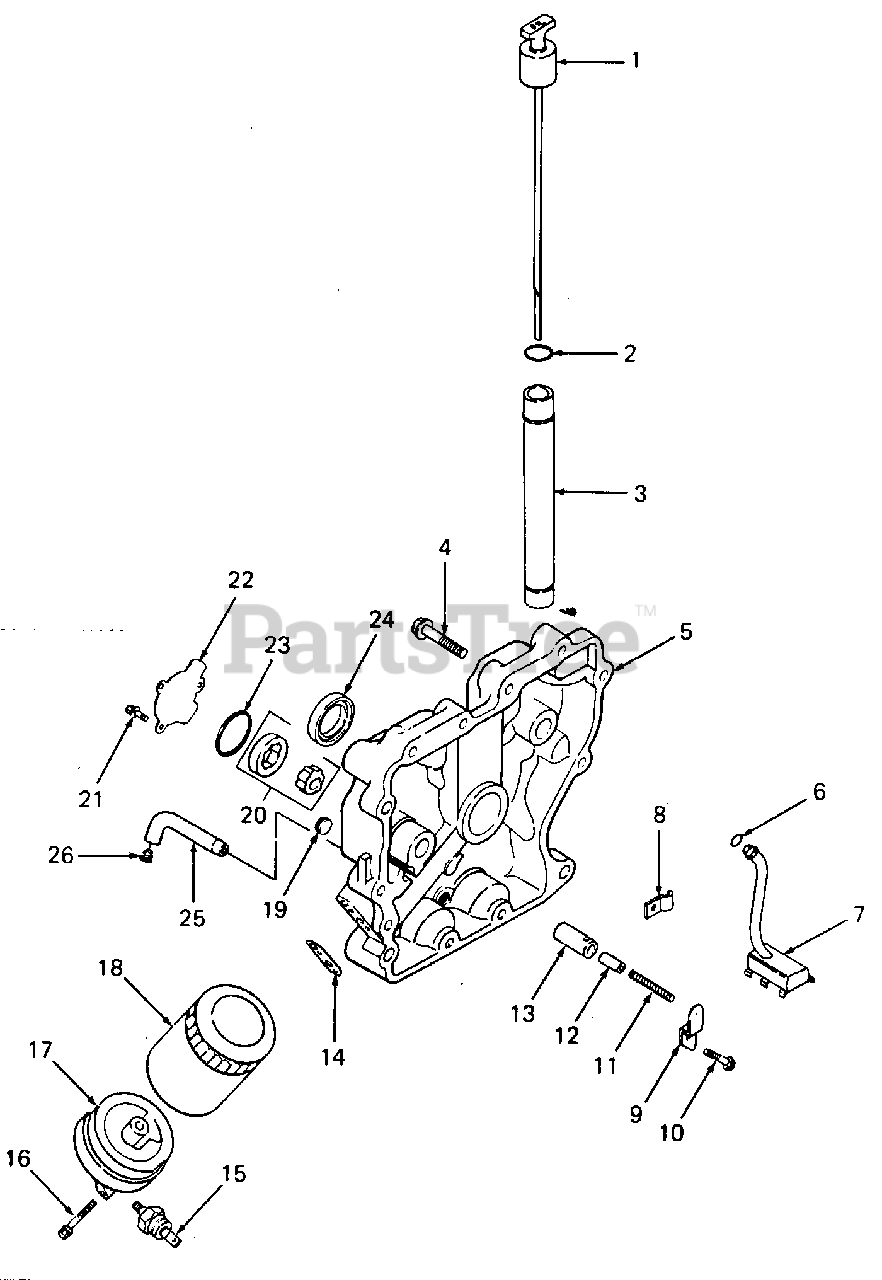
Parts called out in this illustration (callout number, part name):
3	Tube, Oil Fill
4	Screw, Closure Plate, M8 X 1.25 X 45
5	Plate, Closure
7	Oil Pickup
8	Clamp, Oil Pickup Tube
9	Bracket, Oil Pump Relief
10	Screw, Relief Valve Bracket, M10 X 1.5 X25
11	Spring, Oil Pump Relief Valve
12	Piston, Oil Pump Relief Valve
13	Body, Oil Pump Relief Valve
14	Gasket, Oil Filter Adapter
15	Switch, Oil Pressure
16	Screw, Adapter Mount
17	Adapter, Oil Filter
18	Filter, Oil
19	Plug, Drain
21	Screw, Oil Pump Cover, M5 X 0.8 X 16
22	Cover, Oil Pump
23	O-Ring, Oil Pump Cover
24	Seal
25	Pipe, Oil Drain
26	Plug, Oil Drain
